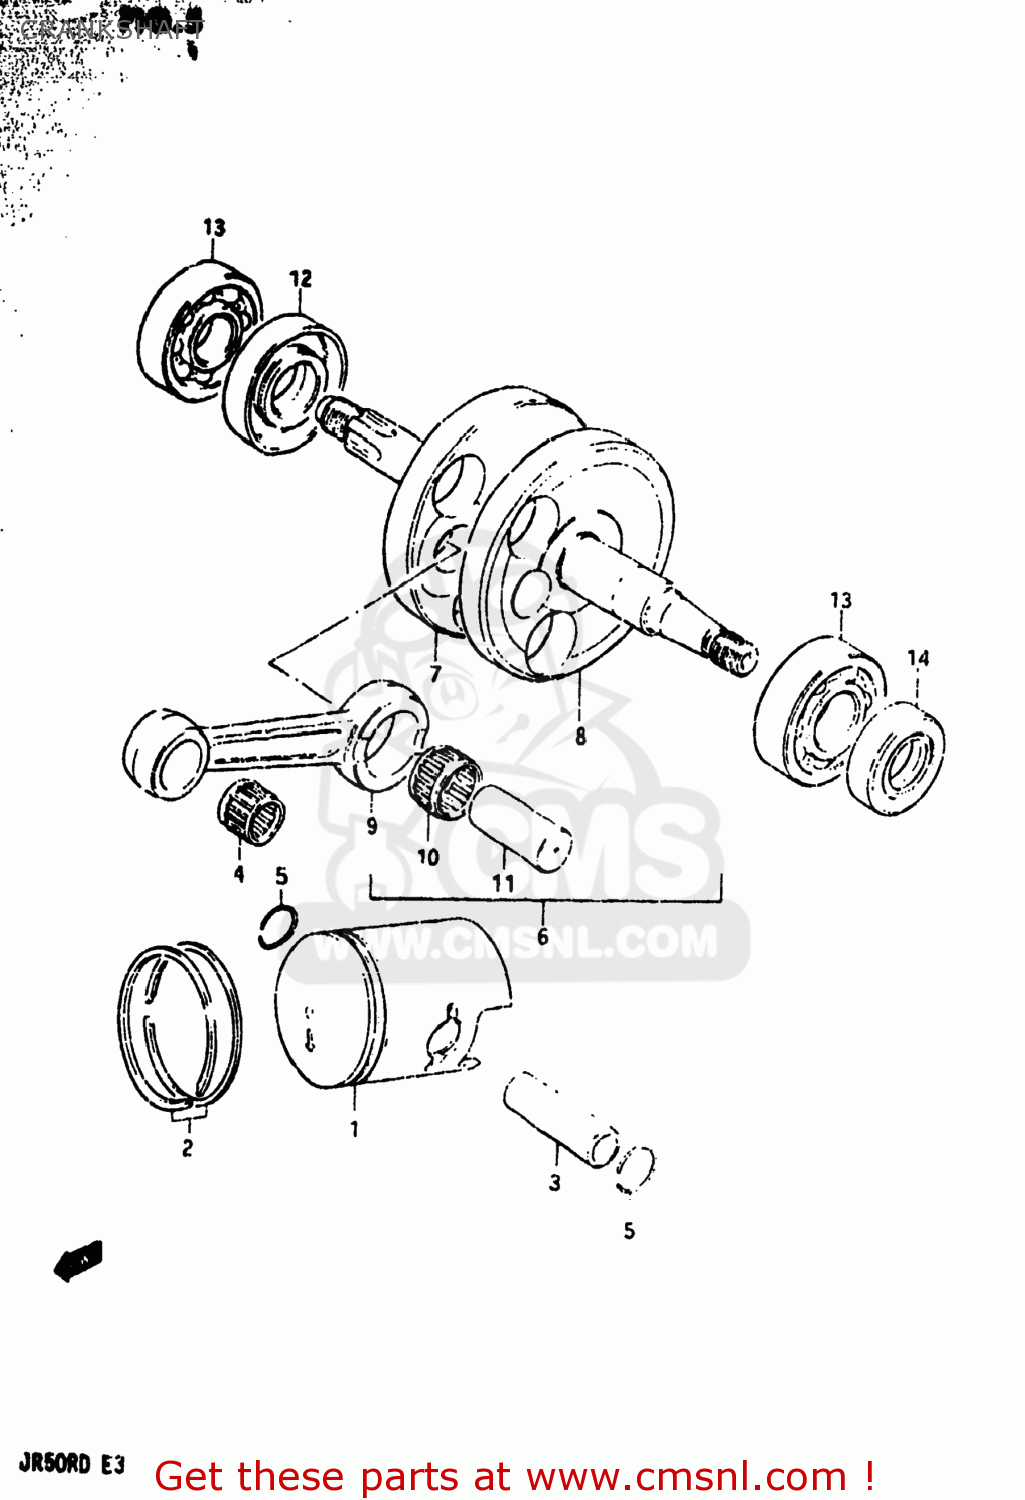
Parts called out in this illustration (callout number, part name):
1	PISTON
2	RING SET,PISTON
3	PIN,PISTON
4	BEARING
5	RING,SNAP
6	CRANKSHAFT ASSY
7	CRANKSHAFT,R
8	CRANKSHAFT,L
9	ROD,CONNECTING
10	BEARING(15X21X9.8)
11	PIN,CRANK
12	SEAL,OIL(22X40X8)
13	BEARING
14	OIL SEAL (17X29X7)
